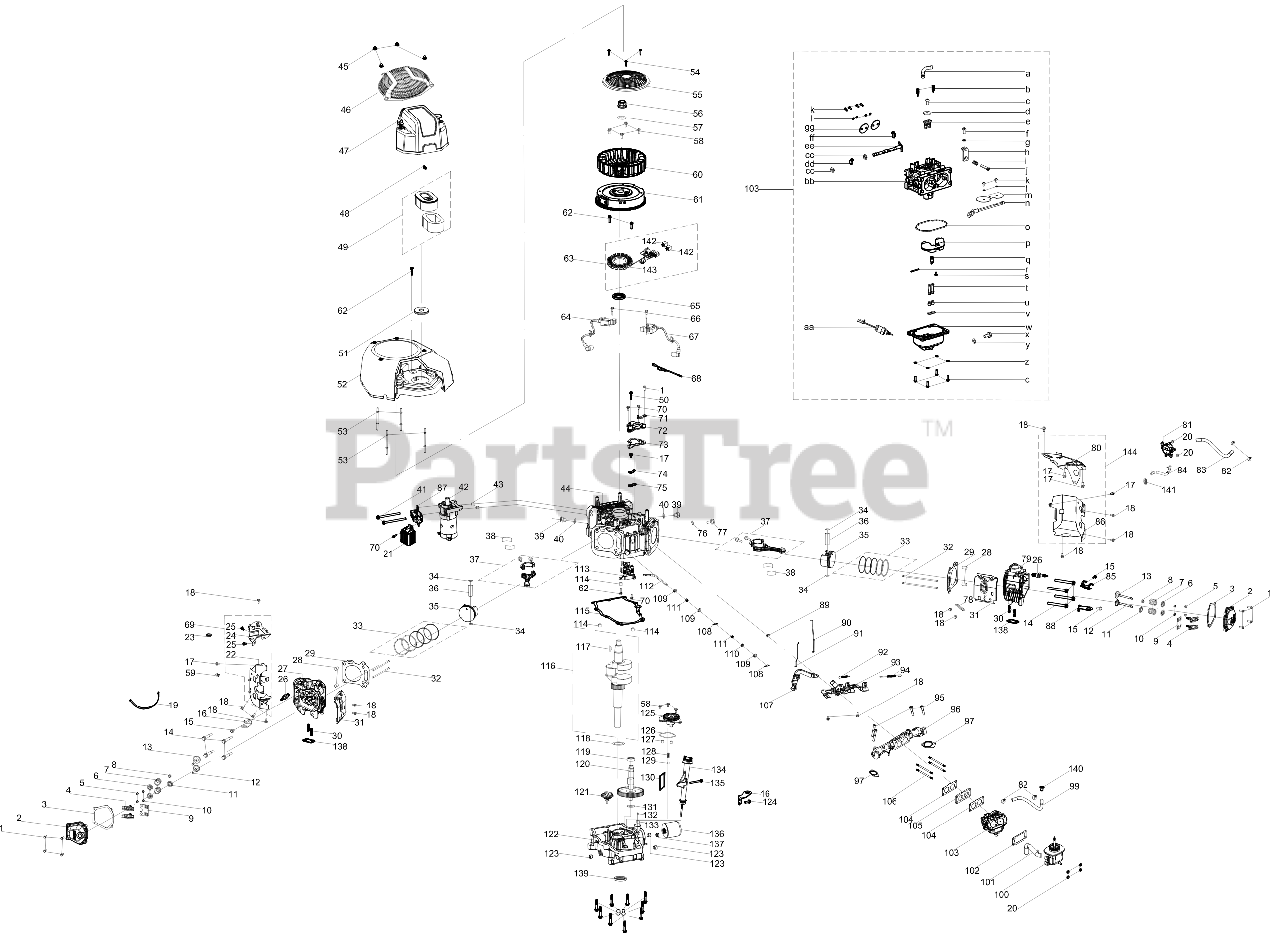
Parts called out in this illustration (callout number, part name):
1	BOLT M6 x 22
2	VALVE COVER
3	VALVE COVER GASKET
4	ROCKER ARM ASSEMBLY
5	EXHAUST VALVE ADJUSTER
6	VALVE SPRING SEAT
7	VALVE SPRING
8	INTAKE VALVE SEAL
9	PUSH ROD GUIDE
10	VALVE CAP
11	VALVE SPRING RETAINER
12	EXHAUST VALVE
13	INTAKE VALVE
14	HEX HEAD BOLT - M10X1.25X87
15	HEX HEAD BOLT M8X16
16	LIFT HOOK BRACKET - LH
17	BOLT M6-1 x 10 GR8.8
18	BOLT M6-1 x 12 GR8.8
19	CABLE TIE - 3 x 150
21	REGULATOR ASSEMBLY
22	CYLINDER HEAD BAFFLE
23	HEAT SHIELD GROMMET
24	FLYWHEEL SHROUD - LH
25	HEX HEAD SCREW M6X10
26	SPARK PLUG
27	CYLINDER HEAD - LH
29	CYLINDER HEAD GASKET
30	STUD M8 x 36
33	PISTON RIN SET
34	PISTON PIN SNAP RING
35	PISTON ASSEMBLY
36	PISTON PIN
37	CONNECTING ROD
38	CONNETING ROS BEARING
39	HEX HEAD BOLT M14-1.5X1.5
40	FLAT WASHER 14X1.5X22
41	HEX HEAD BOLT M8X110
42	ELECTRIC STARTER
45	ACORN NUT
46	SHROUD FAN COVER
47	AIR FILTER COVER ASSEMBLY
49	AIR FILTER ELEMENT
50	BOLT-M6-1 x 28 GR8.8
52	BLOWER HOUSING
53	STUD - M6-1.0X69.8X117
54	BOLT 5.5 x 25
55	DEBRIS SHIELD
56	NUT M20 x 1.5
57	WASHER 20.5 x 5 x 40
58	BOLT M6-1 x 18 GR8.8
59	PLASTIC SUPPORT CLAMP
60	COOLING FAN
62	BOLT M6-1 x 25 GR8.8
63	CHARGING COIL
64	IGNITION MODULE (LH)
65	OIL SEAL 38 x 58 x 8
66	BOLT-M6-1 x 30 GR8.8
67	IGNITION MODULE (RH)
68	WIRE HARNESS
69	SHROUD ASSEMBLY (LH)
70	BOLT M6 x 16
71	FLYWHEEL GUARD BRACKET
72	BEATHER COVER
73	BREATHER COVER GASKET
74	BREATHER REED BRACKET
75	BREATHER REED ASSEMBLY
76	WASHER 20.5X1.5X18
77	HEX HEAD BOLT M10X1X10
79	CYLINDER HEAD - RH
80	SHROUD (RH)
81	FUEL PUMP
82	HOSE CLAMP
83	FUEL HOSE
85	MOUNTING BRACKET
86	CYLINDER HEAD BAFFLE
87	STARTER RELAY SUPPORT
88	REAR LIFT BRACKET
89	CHOKE LINKAGE LOCK CLAMP
90	THROTTLE LINKAGE
91	CHOKE LEVER
92	GOVERNOR SPRING
93	GOVERNOR GEAR BRACKET ASSEMBLY
94	GOVERNOR SPRING
95	SCREW - M8X50
96	INTAKE MANIFOLD
97	INTAKE MANIFOLD GASKET 9Q78
98	HEX HEAD FLANGE BOLT M8X48
99	FUEL LINE 6.3 x 12.5 x 470
100	INTAKE MANIFOLD
101	BREATHER HOSE
102	AIR FILTER HOUSING GASKET
103	CARBURETOR
104	CARBURETOR GASKET
105	INSULATOR
106	STUD M6-1 x 105
107	GOVERNOR LEVER
108	GOVERNOR SHAFT CLIP
109	FLAT WASHER 8.5X15.8X2
110	GOVERNOR SEAL
111	NEEDLE BEARING 8X12X10
112	GOVERNOR ARM ROD
113	ROACKER ARM
115	CRANKCASE GASKET
116	CRANKSHAFT ASSEMBLY
117	FLYWHEEL KEY
118	WASHER - 38.5X1.0X54
119	CAMSHAFT BEARING
120	CAMSHAFT ASSEMBLY
121	GOVERNOR GEAR
122	CRANKCASE COVER
123	ENGINE PLUG 3/8 NPT
124	HEX HEAD SCREW M8X16
125	OIL PUMP ASSEMBLY
126	OIL PUMP GASKET
127	DOWEL PIN
128	OIL PUMP SPRING
129	OIL PUMP STEEL BALL
130	OIL PUMP SCREEN
131	THRUST WASHER 17.4X25.9X1.0
132	O-RING 13.2X2.65
133	CRANKCASE OIL PASSAGE PIN
134	DIPSTICK ASSEMBLY
135	SCREW M6-1:50:CL5.
136	ENGINE OIL FILTER
137	SCREW JOINT OIL FILTER ADAPTER
138	EXHAUST GASKET
139	OIL SEAL 38 x 58 x 8
143	CHARGING COIL
144	SHROUD ASSEMBLY (RH)
